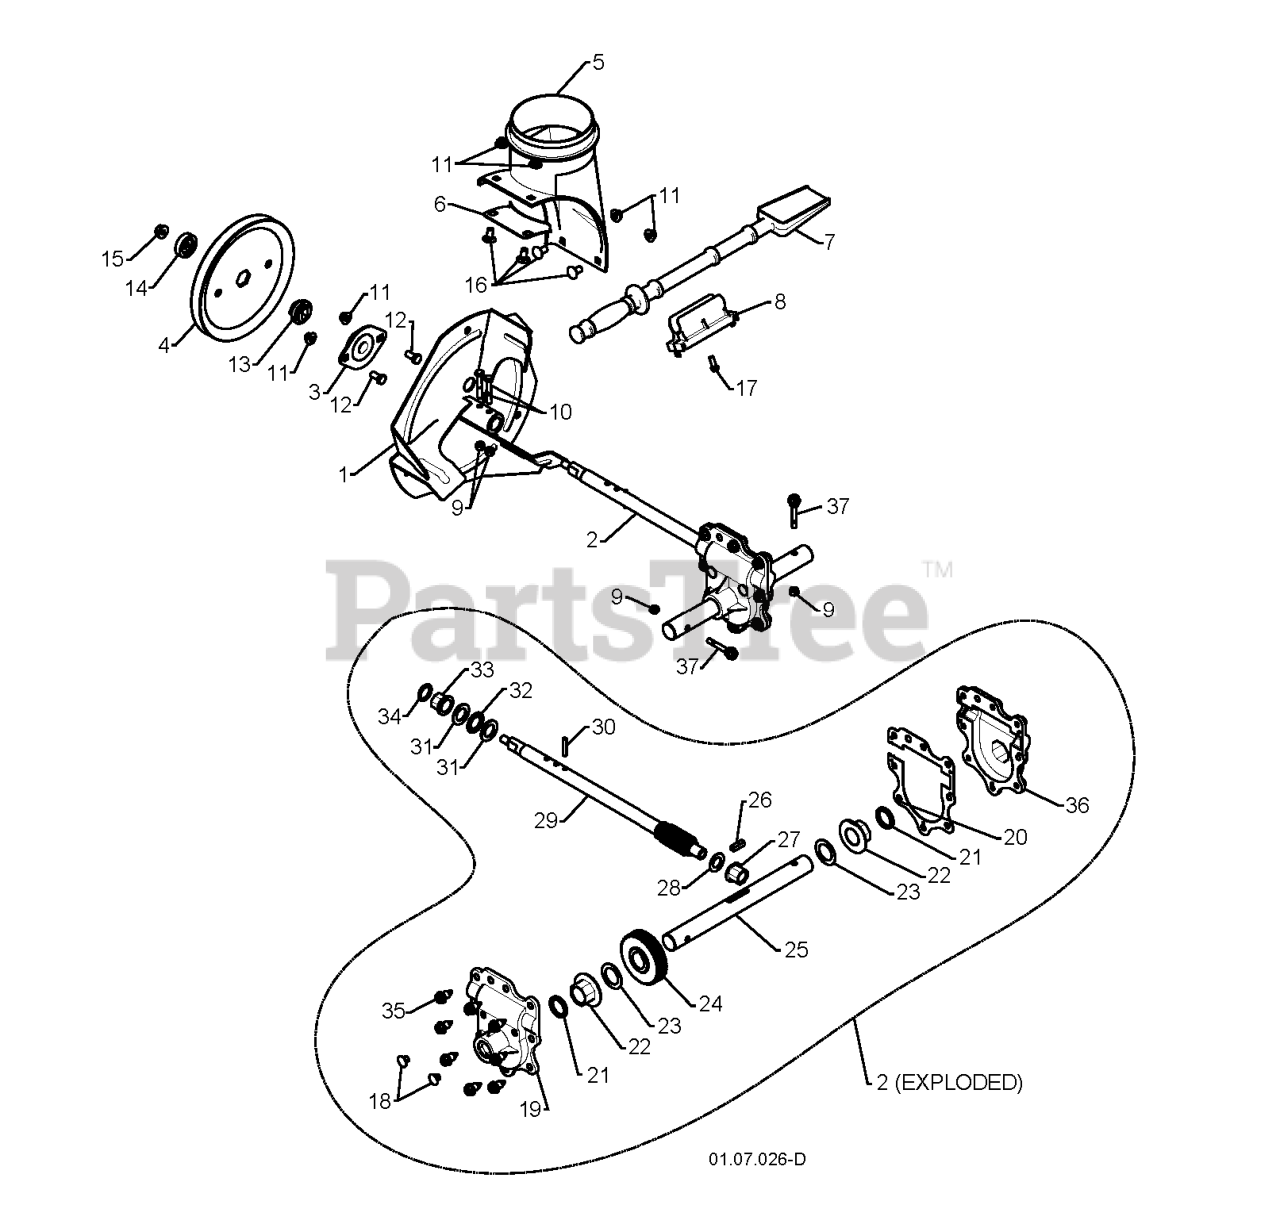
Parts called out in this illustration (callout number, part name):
1	IMPELLER.WELDMENT.BLACK
2	GEARBOX.ASM.AUGER.D-SHAFT
3	BEARING FLANGE
4	PULLEY.FLANGE.IMPELLER
5	BASE DISCHARGE CHUTE
6	BRACKET, CORNER DISCHARGE
7	CLEAN OUT TOOL
8	CLIP.CLEANOUT.TOOL
9	LOCKNUT.NYLOC.1/4-20
10	SCREW.HEX.HD1/4-20X
11	NUTNYLOK.FLRANGE.5/16-18
12	BOLT, HEX HEAD 5/16-18
13	HUB.IMP.PULLEY.D-SHAFT
14	SLEEVE.IMP.PULLEY.D-SHAFT
15	NUT LOCK FLG 3/8-16 UNC
16	BOLT.CARRIAGE.5/16-18X
17	SCREW.HWH.13-16-5.8.BZP
18	CASE PLUG
19	GEAR.BOX.COVER.RIGHT.SIDE
20	GASKET.GEAR.BOX
21	OIL SEAL
22	FLANGE BUSHING-1"
23	WASHER TRUST 1"
24	WORM GEAR
25	AUGER SHAFT
26	KEY, SQUARE 1/4 X .875
27	FLANGE BUSHING-5/8
28	WASHER, THRUST 5/8
29	SHAFT.IMPELLER.D-SHAFT
30	PIN, ROLL 3/16 X 1-1/8
31	WASHER, THRUST 3/4
32	BEARING TRUST 3/4 NTA-1220
33	BUSHING, FLANGE 3/4
35	HEX SCREW-5/16 X 3/4
36	GEAR.BOX.COVER.LEFT.SIDE
37	BOLT.SHOULDER.SHEAR.1/4-20.
